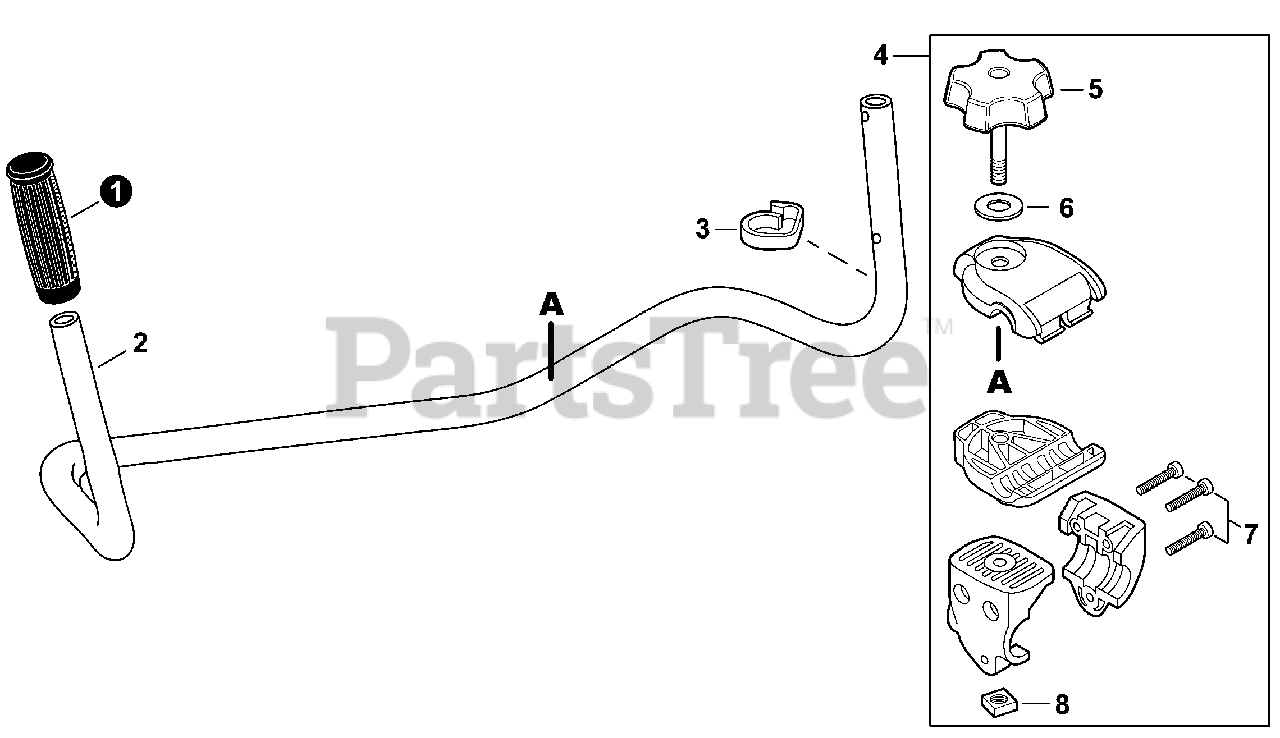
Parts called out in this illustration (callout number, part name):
1	GRIP, HANDLE
2	U-HANDLE
4	BRACKET KIT, U-HANDLE
5	KNOB, SCREW M8
6	WASHER 8
7	BOLT, TORX 5×25
8	NUT 8×1.25
